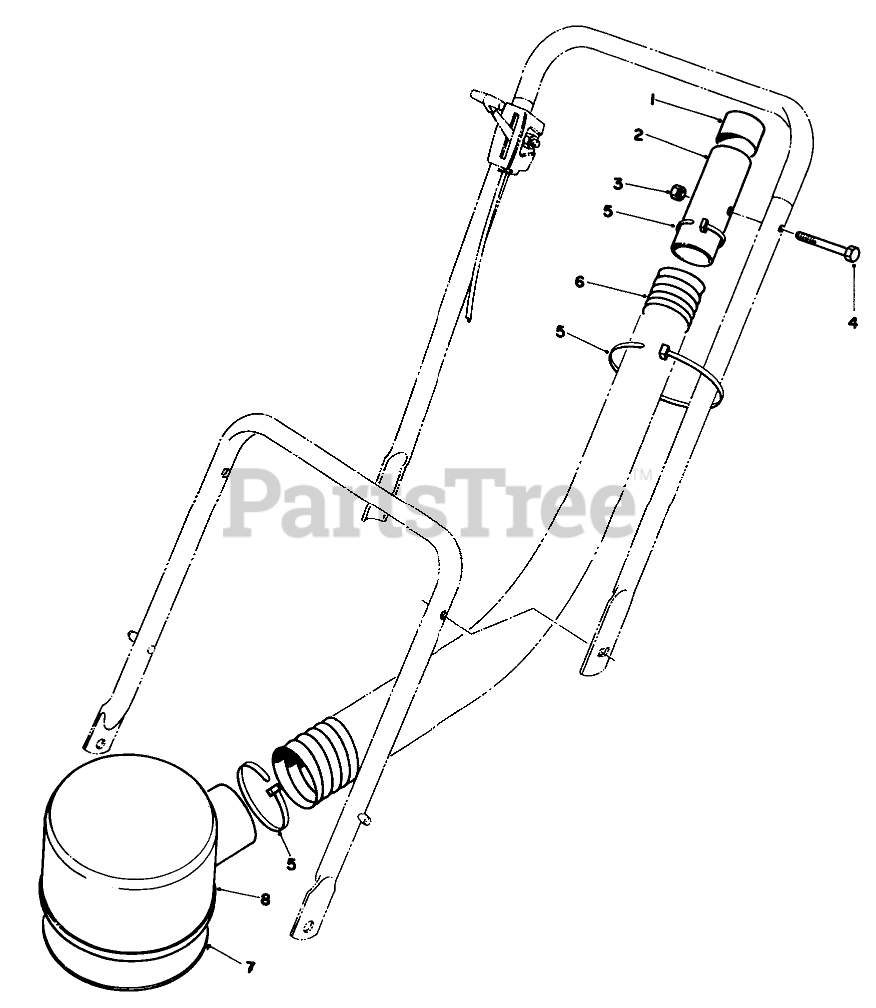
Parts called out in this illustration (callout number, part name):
1	BLACK CAPLUG
2	AIR CLNR HOSE TIP
3	NUT-LOCK, CONE
4	SCREW-HH
5	TIE-CABLE
6	AIR CLEANER HOSE
7	AIR CLEANER BASE
8	Air Cleaner Cover
